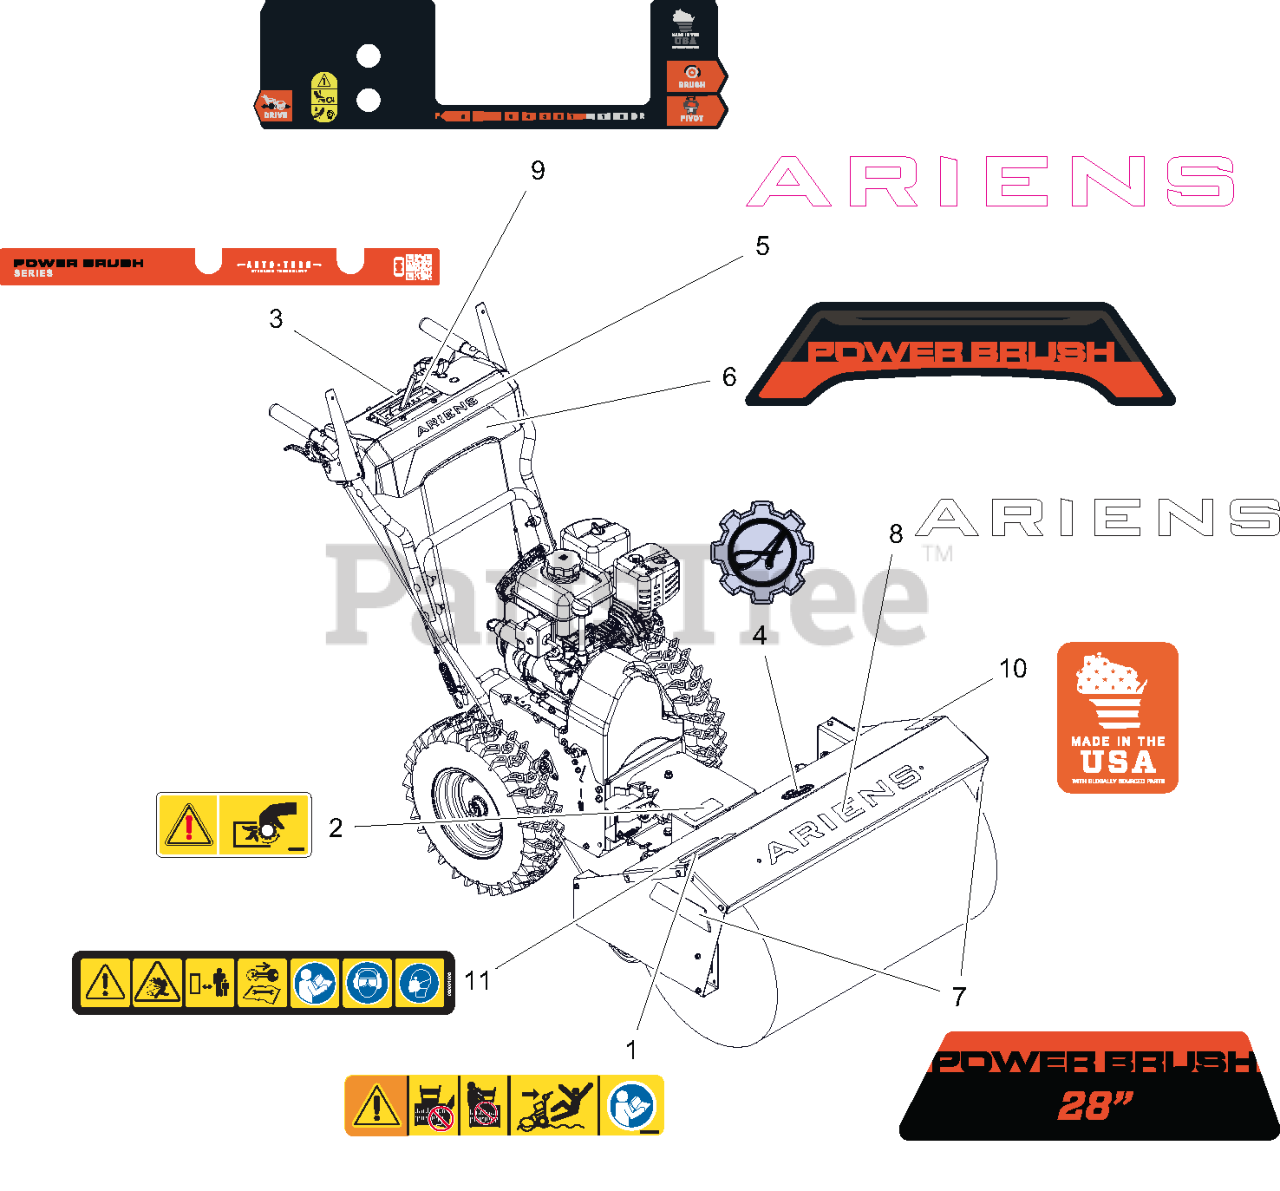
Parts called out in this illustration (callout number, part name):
1	DECAL, DANGER -POWER BRUSH-CE
2	DECAL, PTO WARNING
3	DECAL, DASH - SM BRUSH
4	DECAL, ARIENS - GEAR BADGE
5	DECAL- ARIENS - 7.46"
6	DECAL, BEZEL - POWERBRUSH
7	DECAL, POWERBRUSH - 28
8	DECAL, ARIENS - 19.0"
9	DECAL, CONTROL - SM BRUSH
10	DECAL- MADE IN USA
11	DECAL, SAFETY, DASH, BRUSH
